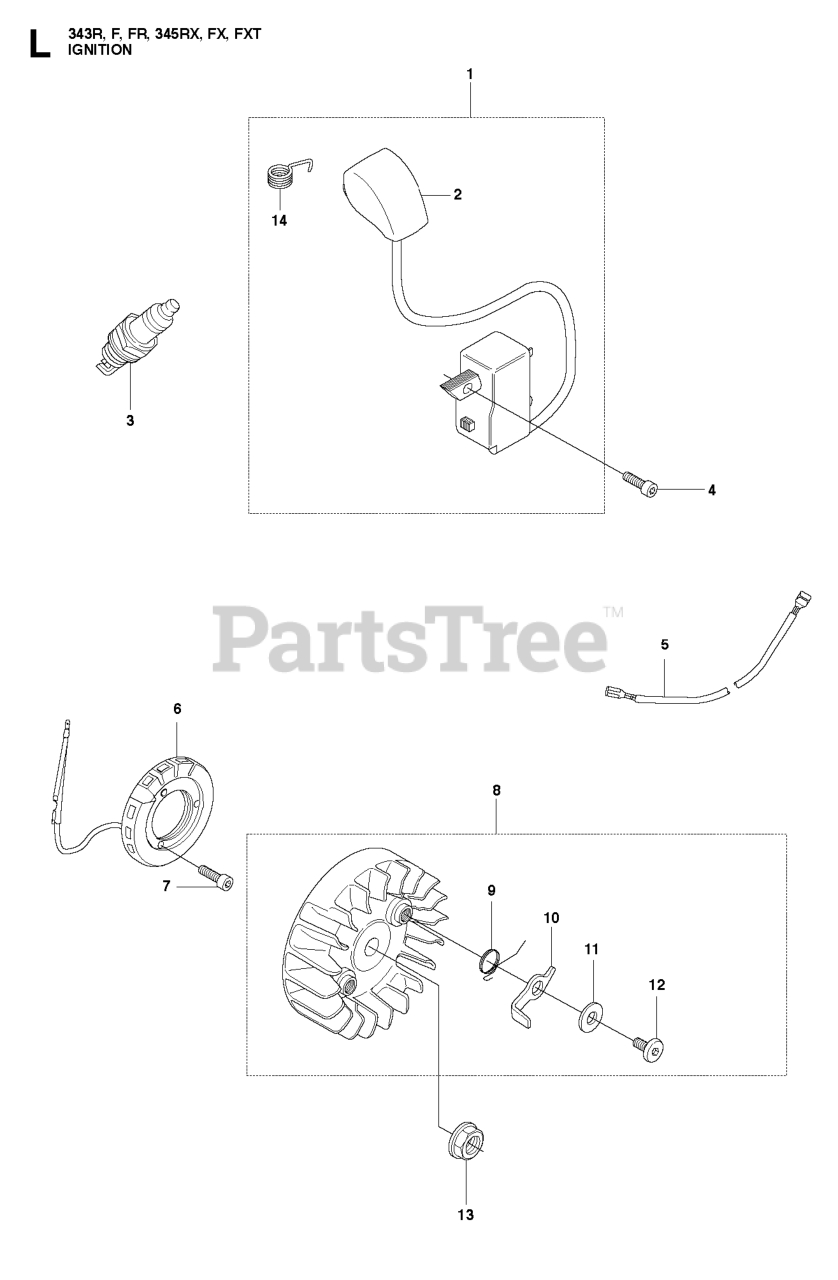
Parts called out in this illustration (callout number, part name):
1	IGNITION MODULE
3	SPARK PLUG RCJ6Y NLA
5	SHORTING LEAD
6	GENERATOR
7	SCREW
8	Flywheel
8	FLYWHEEL
9	SPRING
10	STARTER PAWL
13	NUT W/ WASHER
14	SPRING
